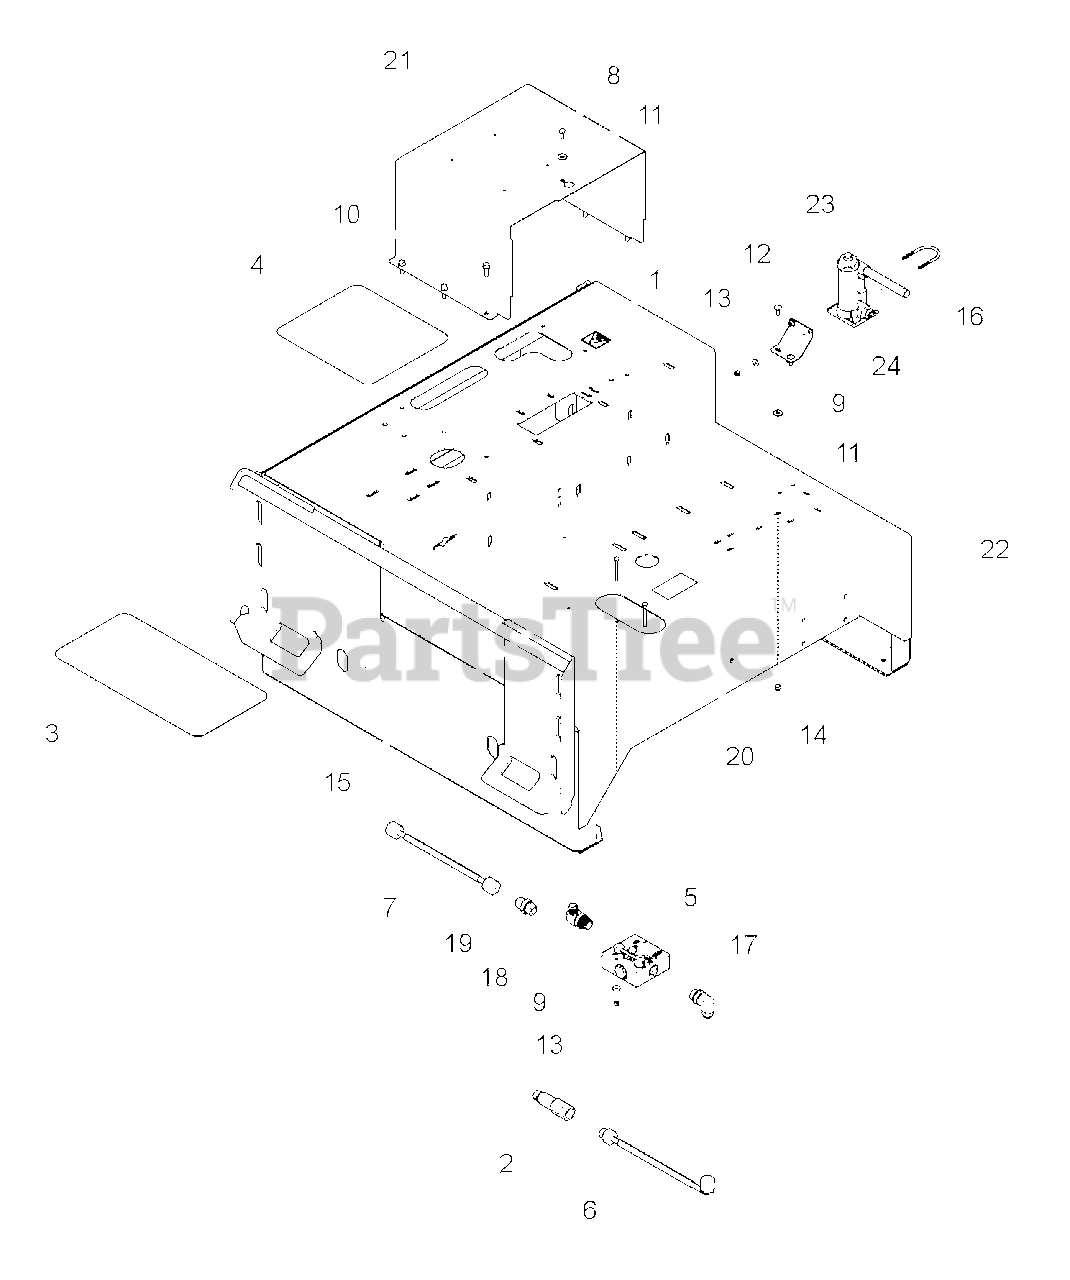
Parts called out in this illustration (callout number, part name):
1	DECAL, SHIELD DANGER ISO
3	TREAD, SAFETY
4	TREAD, SAFETY
5	VALVE, 30 GPM FLOW CONTROL
6	HOSE, .75 X 119 -12MORING/-12FMJIC90
7	HOSE, .75 X 40 -12FMJIC/-12FMJIC
8	BOLT, 5/16-18 X 3/4 GR5 HEX HD
9	WASHER, 1/4 FLAT
10	SCREW, 3/8-16 X 1 T23 HWH MAGNI 565 SILVER
11	WASHER, 5/16 FLAT
12	BOLT, 5/16-18 X 7/8 GR5 CRG
13	NUT, 1/4-20 NE NYLOCK
14	NUT, 5/16-18 NE NYLOCK
15	BOLT, 1/4 X 2-1/2" HHCS GR5 ZP
16	U-BOLT, 1/4 X 1-1/2 PIPE
17	ADAPTER, -12MORING/-12MJIC 90 DEG
18	ADAPTER, -12MORING/-10MJIC 90 DEG
19	ADAPTER, -12MORING/-12MJIC
20	DECAL, FEED SPEED
21	WELDMENT, HYDRAULIC MOTOR COVER (CH800H)
22	WELDMENT, CHIPPER BASE
23	JACK, HYDRAULIC 2 TON
24	PLATE, JACK MOUNT
